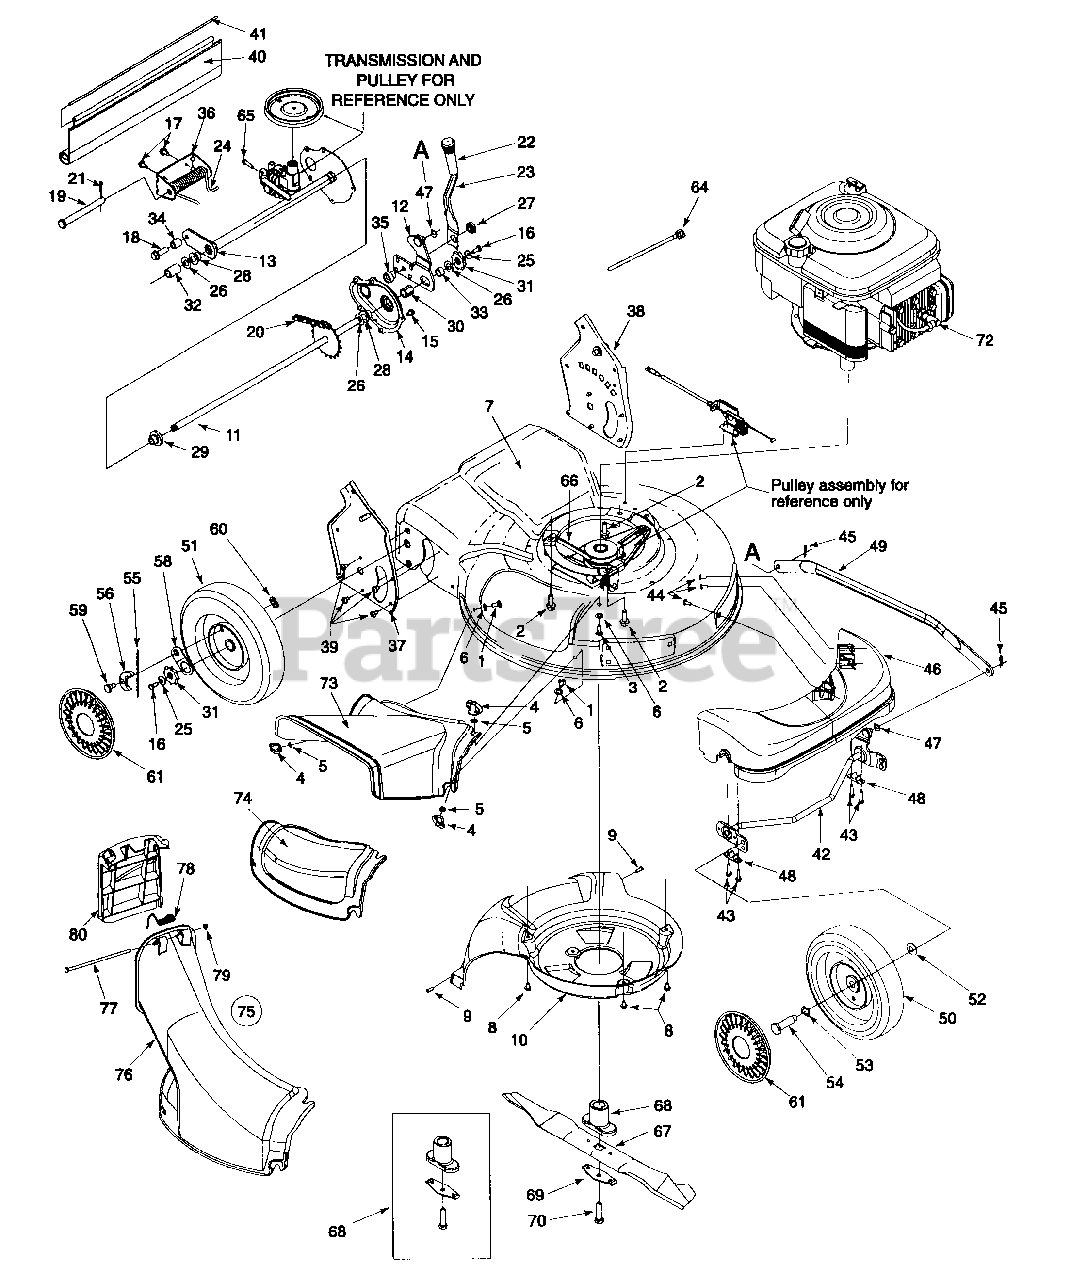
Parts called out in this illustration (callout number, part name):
1	Scr. Carr. 1/4-20 x .62
2	Scr. TT:3/8-18:1.00
3	Scr. 1/4-20 x .750
4	Wing Nut 1/4-20
5	Nut, Push .25 I.D.x.50O.D.
6	Wash. Fl. .334 I.D. x .62 x .03
7	Deck-21" (Code N)
8	Scr. TT. 1/4-20 x .375
10	Baffle
11	Rear Axle Ass'y
16	Cap Screw HH 1/4-20 x .620
17	Scr., AB 1/4-14 x .825
18	Scr., 3/8 116 x .25
19	Clevis Pin .50 Dia. x 4.82 Lg.
20	Chain-Endls. #48 .500P x 24L
21	Cotter Pin .125 O.D. x .75
23	Spring Lever
24	Torsion Spring
25	Bell Wash. .285 x .75 x .082
26	Fl. Wash. .508 I.D. 1.000 x .020
27	Nut Shld. .825 Dia. x .165 Lg.
28	Hx. Flg. Brg. .506 I.D. x .590 L.
29	Hx. Flg. Brg. .506 I.D. x .715 L.
30	Hx. Slv. Brg. .504 I.D. x .830 L.
31	Wheel Rachet
32	Spa. .550 I.D. x .750 O.D.
33	Spa. .51 .D. x .70 O.D. x 38 L.
34	Spa. .385 x .624 x .700
35	Shld. Spa. .385 I.D. X .715 Lg.
38	Handle Brkt. Assembly L.H.
39	Scr. AB 1/4-14 x .500
40	Trail Shield
41	Trail Shield Wire
42	Fr. Axle Ass'y.
43	Hx Scr. Wash Hd. Hi.-Lo.
44	Scr. Torx, Truss Hi.-Lo.
45	Cotter Pin .072 x 1.12 Lg.
46	Fr. Axle Cover
47	Bowed Washer
48	Bush. Block .505 Dia. x .62
49	Control Arm
50	Wheel 8 x 2 Link Black
51	Wheel 9 x 2 Link Beige, Sleeve
52	Spr. Wash. .401 x .870 x .063
53	Wave Wash. .510 x .750 x .017
54	Shldr Scr. .498 x 1.445 x 3/8-16
55	Spring, Ratchet, Plastic
56	Pawl - R.H.
58	Ratchet Pawl Plate
60	Top Lock Tab Weld Nut 1/4-20
61	Hubcap
64	Scr. Hi-Lo #10 x 1.25
66	Belt
67	21" Mulching Blade
68	Blade Adapter Kit
69	Blade Bell Support
70	Hex Bolt 3/8-24x2.5" Lg.
72	Spark Plug Insulator
73	Side Discharge Chute
74	Mulch Cover
75	Scr. Hex. 5/15-18
76	Cable Tie
